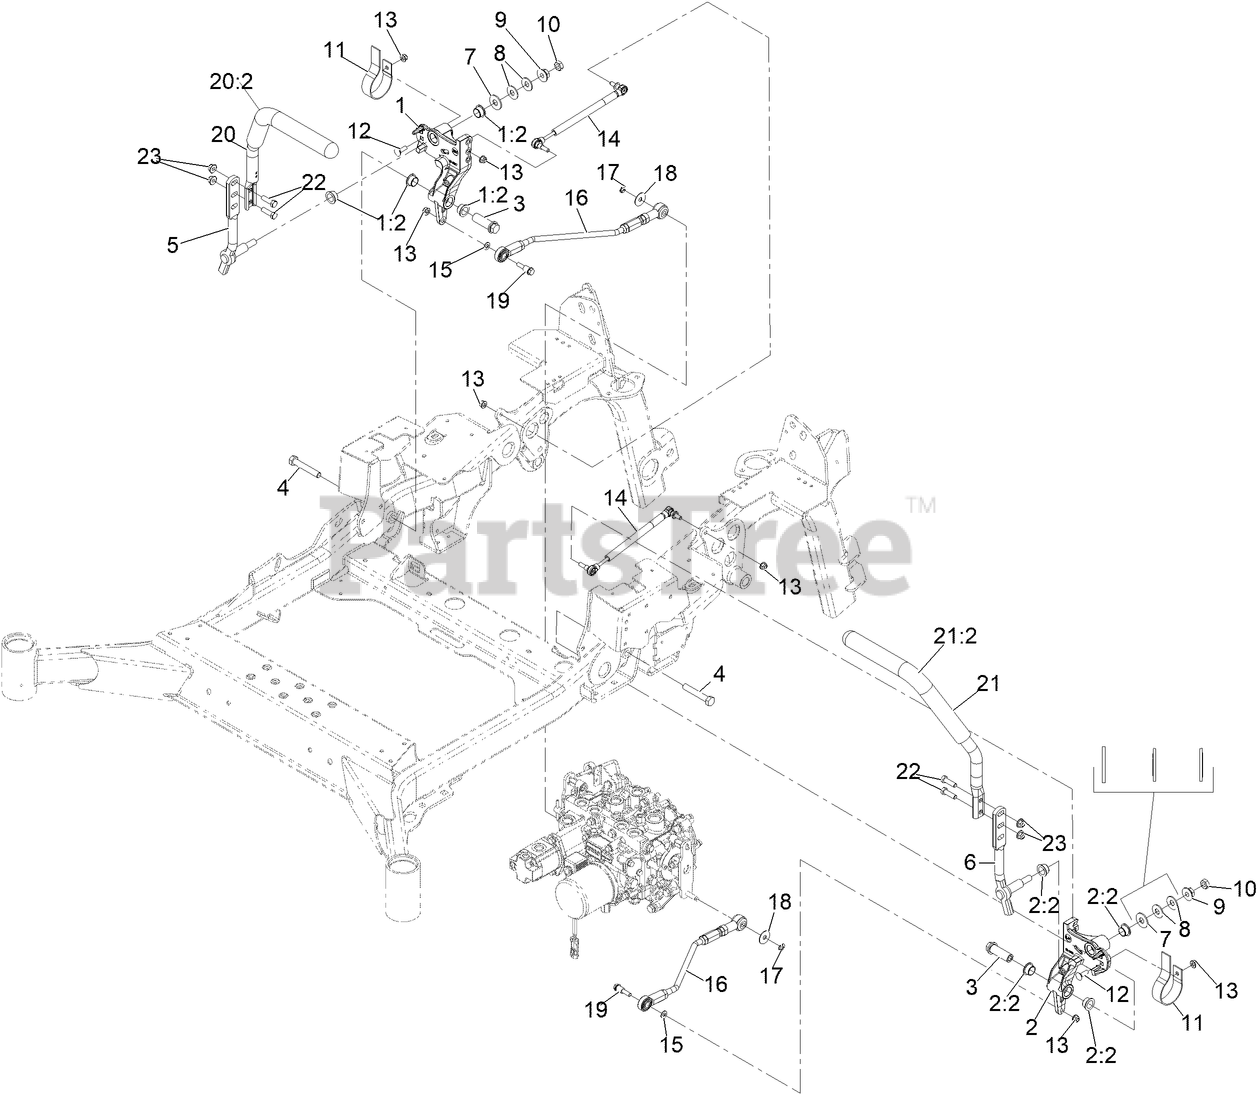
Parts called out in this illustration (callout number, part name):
1	RH MOTION CONTROL AND BUSHING ASM
1:2	BUSHING-FLANGE
2	LH MOTION CONTROL AND BUSHING ASM
2:2	BUSHING-FLANGE
3	HUB-THREADED
4	SCREW-HH
5	LEVER-CONTROL MOTION, RH
6	LEVER-CONTROL MOTION, LH
7	WASHER-FLAT
8	WASHER-SPRING
9	NUT-HF
10	NUT-JAM
11	SPRING-LEAF
12	BOLT-CARR
13	NUT-HF, NI
14	DAMPER-CONTROL, MOTION
15	WASHER-PLAIN
16	ASM, FRONT LINKAGE ROD
17	RING-RETAINING
18	WASHER-PLAIN
19	BOLT-SHOULDER,HHF
20	RH STEERING HANDLE ASM
20:2	GRIP-CONTROL, LEVER
21	LH STEERING HANDLE ASM
21:2	GRIP-CONTROL, LEVER
22	SCREW-HH
23	NUT-HF, NI
